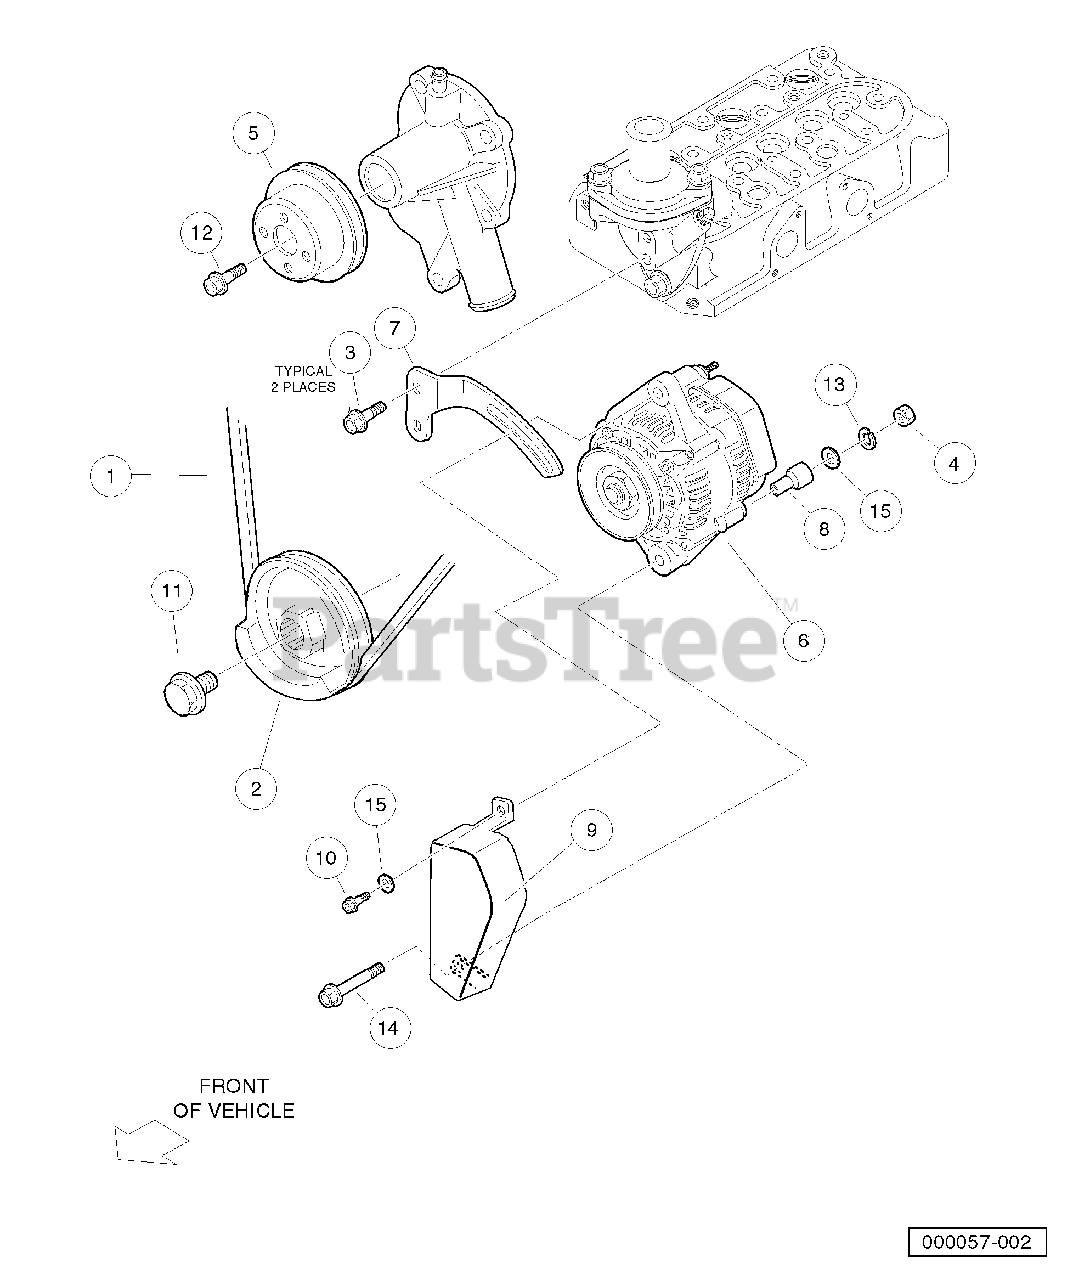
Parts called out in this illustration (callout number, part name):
2	Pulley, Fan Drive
3	Bolt, M6 X 1 X 20
4	Nut, M8, Plate
5	Pulley, Water Pump
6	Alternator, 40-Amp
7	Stay, Alternator Assy, D722
8	Collar, Alternator Assy, D722
9	Cover, Alternator Assy, D722
10	Bolt, Alt, D722, Adjuster
11	Bolt, Alt, D722, Drive Pulley
12	Bolt, D722, Drive Pulley
13	Washer, Spring, D722, Starter
14	Bolt, Alternator, Lower
15	Washer, Alternator, Upper
